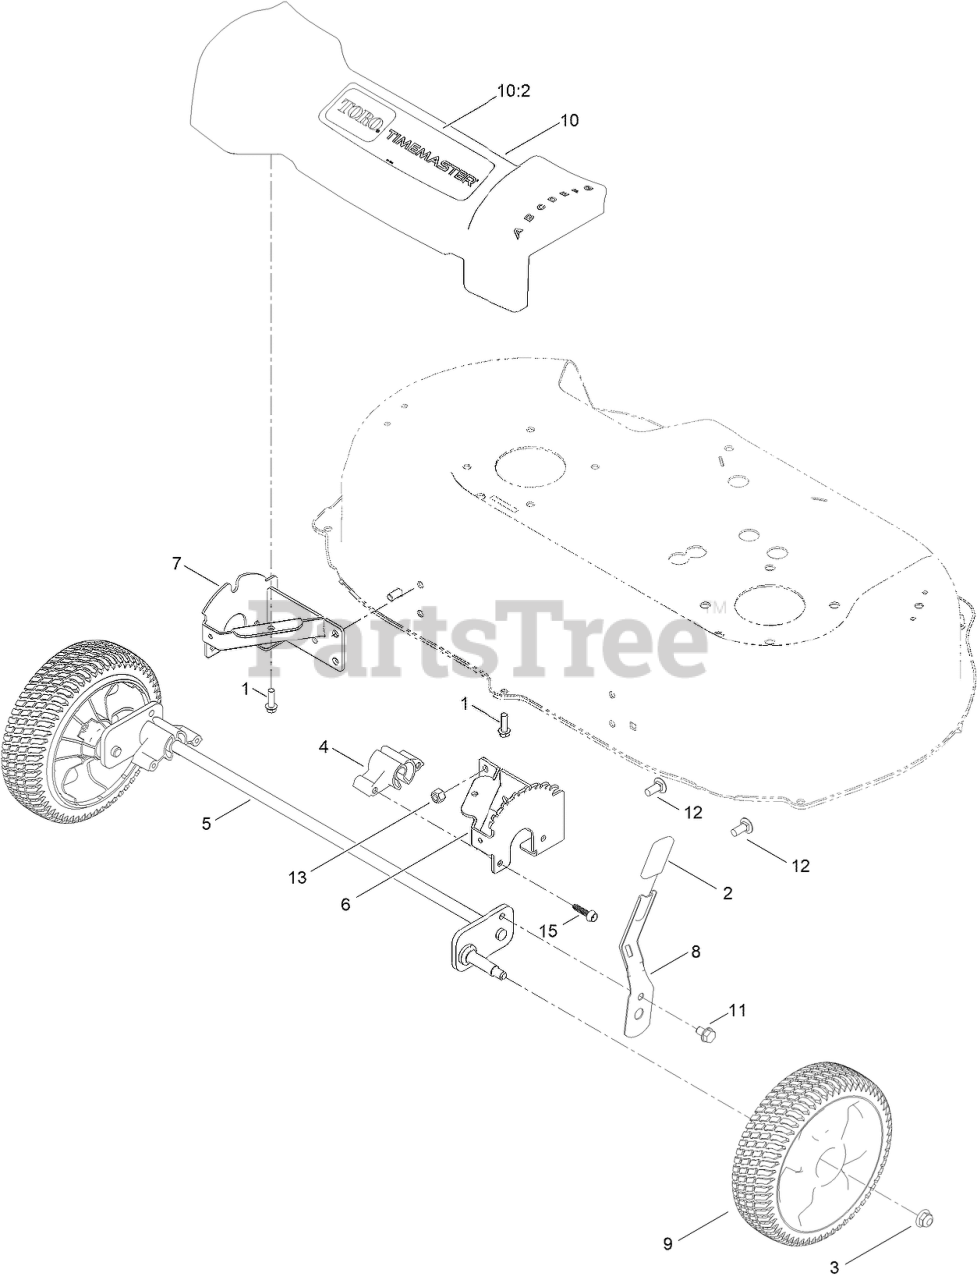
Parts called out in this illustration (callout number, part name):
1	SCREW-HWH
2	GRIP-LEVER
3	NUT-HF, NI
4	BUSHING-PIVOT, FRONT
5	FRONT AXLE ASM
6	PLATE-HOC, LH
7	PLATE-HOC, RH
8	ARM-SPRING
9	8 INCH WHEEL ASM
10	FRONT COVER ASM
10:2	DECAL-COVER, FRONT
11	SCREW-HWH
12	SCREW-CARR
13	NUT-LOCK, NI
15	SCREW-FLANGE, PLASTIC
